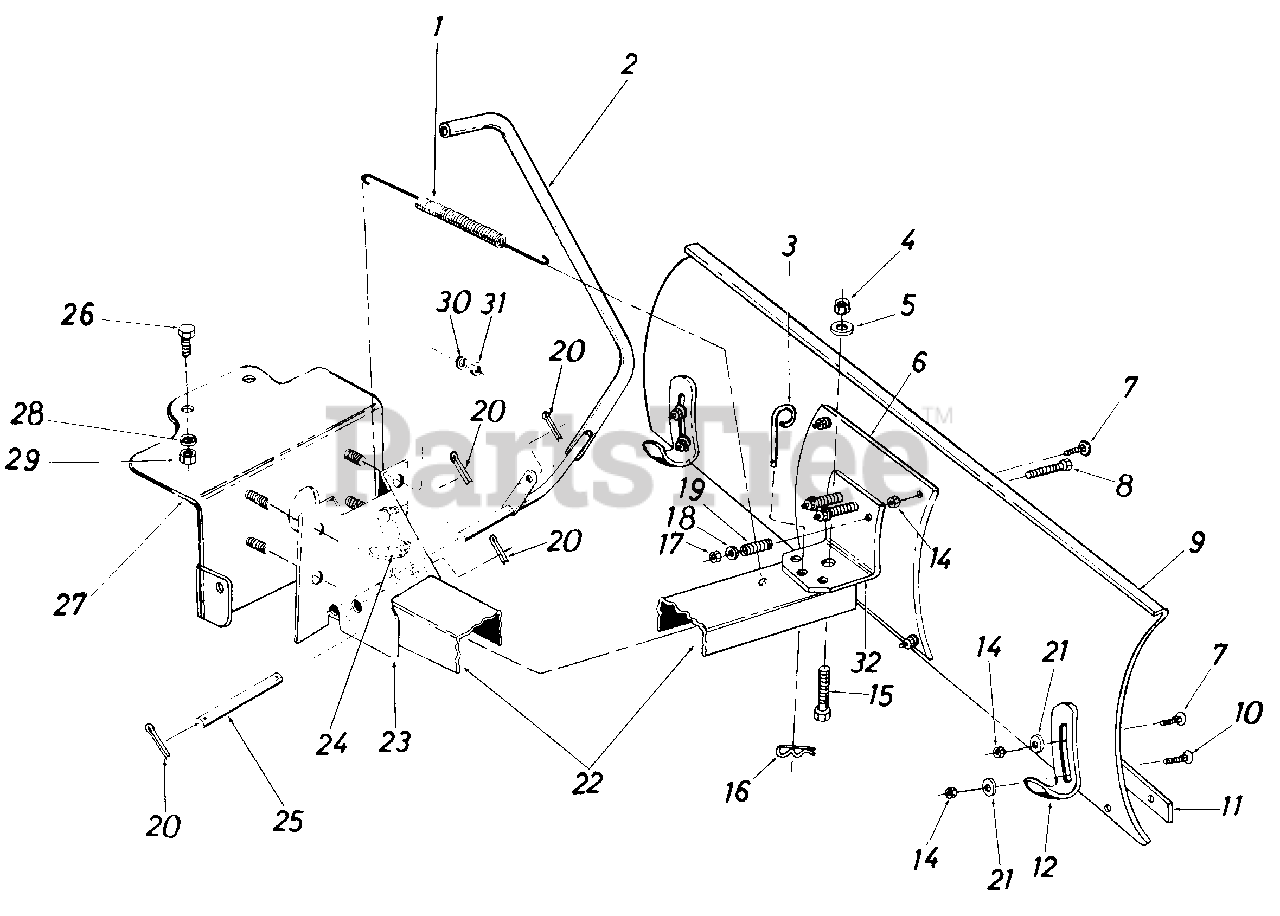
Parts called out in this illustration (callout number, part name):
1	Extension Spring
2	Lift Handle Ass'y.
3	Pivot Lock Pin
4	Hex Cent. L.-Nut 1/2-13 Thd.
5	Fl.-Wash. 17/32 I.D. x 1.25" Lg.
6	Reinforcement Plate
7	Carriage Bolt 5/16-18 x .75" Lg.
8	Hex Scr. 3/8-16 x 3.75" Lg. Grade 5
9	42" Blade
10	Carriage Bolt 5/16-18 x 1.00" Lg.
11	42" Wear Plate
12	Shoe Skid
14	Hex Cent. L.-Nut 5/16-18 Thd.
15	Hex Scr. 1/2'-13 x 1.25" Lg.
16	Hair Pin Cotter
17	Hex Cent. L.-Nut 3/8-16 Thd.
18	Fl .-Wash . 3/8 " I . D.
19	Compression Spring
20	Cotter Pin 1/8" Dia. x 1.00" Lg.
21	Fl.-Wash. 5/16" I.D.
22	Push Bar Channel
23	Pivot Support Bracket
24	Li ft Li n k
25	Channel Pivot Shaft
26	Hex Scr. 3/8-16 x 1.00" Lg. Grade 5
27	Support Bracket Ass'y.
28	L.-Wash. 3/8 I.D.
29	Hex Nut 3/8-16Thd.
30	L.-Wash. 3/8" I.D.
31	Hex Jam Nut 3/8-16 Thd.
32	Support Bracket
